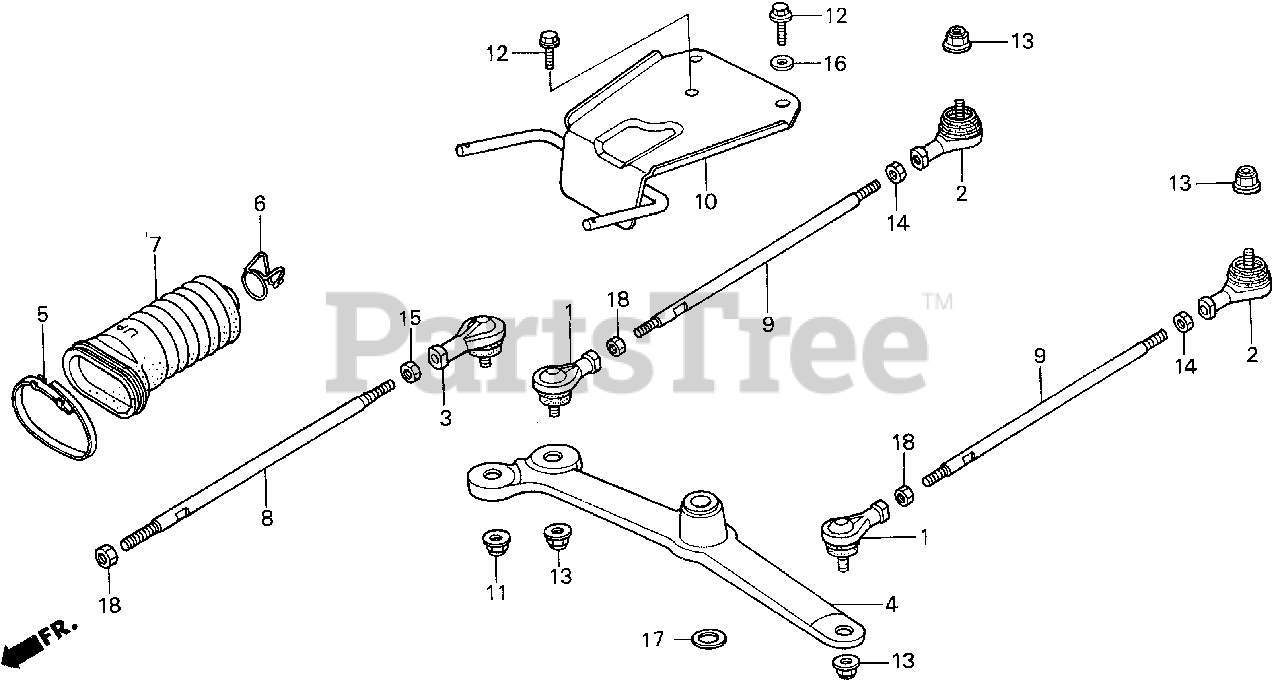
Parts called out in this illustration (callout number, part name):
1	JOINT, R. BALL (ER12)
2	JOINT, L. BALL (ER12)
3	JOINT, L. BALL (ER10)
4	ARM, RR. STEERING
5	BAND, RELAY ROD SEAL
6	CLIP, TIE ROD
7	SEAL, RELAY ROD
8	ROD, RR. STEERING RELAY
9	TIE ROD, RR.
10	BRACKET B, OIL TANK
11	NUT, SELF-LOCK (10MM)
12	BOLT, FLANGE (8X20)
13	NUT, SELF-LOCK (12MM) (SATO RASHI)
14	NUT, L. HEX. (12MM)
15	NUT, L. HEX. (10MM)
16	WASHER, SEAL (8MM)
17	WASHER, THRUST (17MM)
18	NUT, HEX. (12MM)
